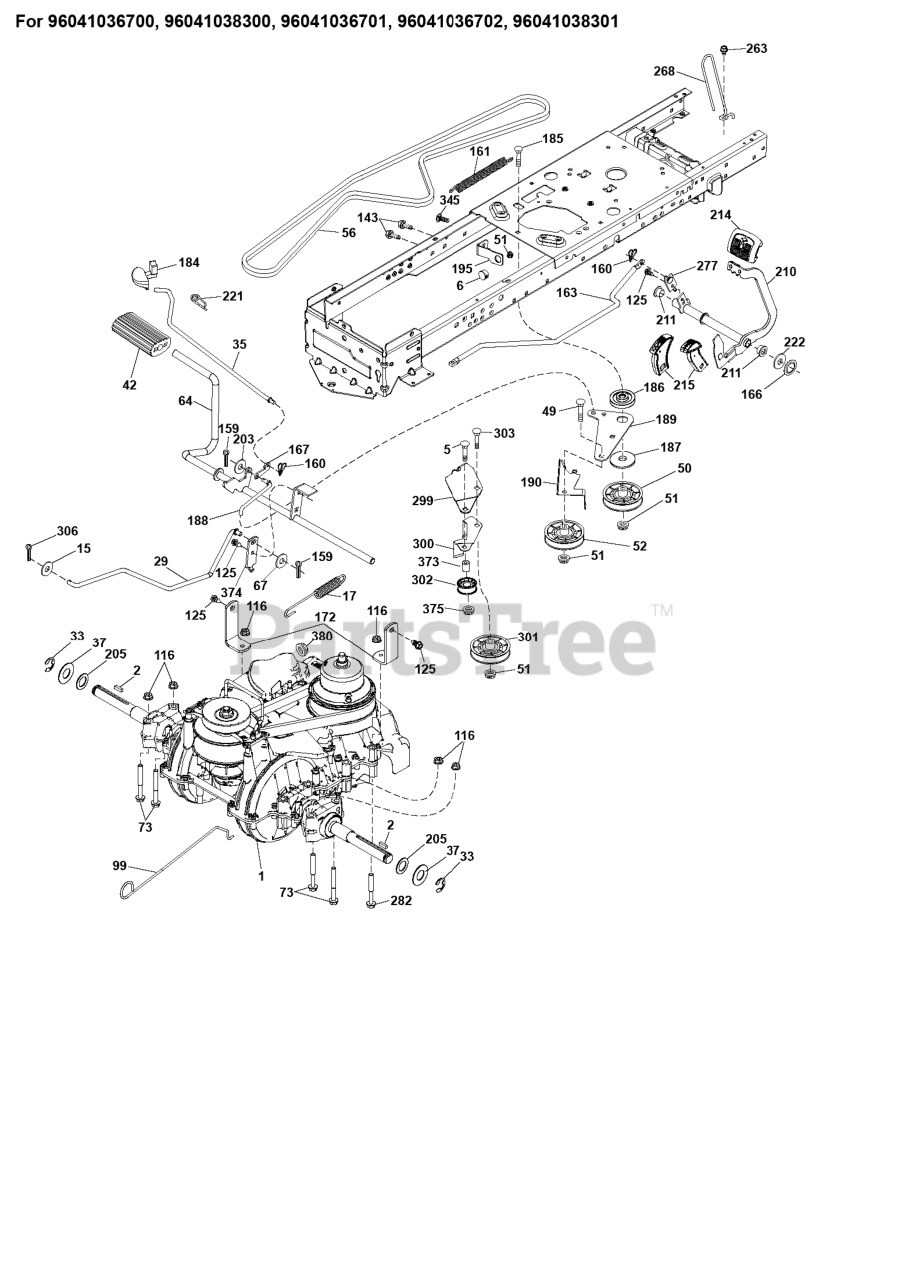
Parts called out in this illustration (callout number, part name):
1	TRANSAXLE.VARIATOR.PEDAL.SD
2	SQUARE KEY
6	BUSHING.SNAP.NYL.BLK.
15	WASHER
17	SPRING.BRAKE.VARIATOR
29	BRAKE.VARIATOR.SD3
35	ROD.CNTRL.PARK.PREDATOR.LT.TEX
37	WASHER.HARDENED
42	PEDAL COVER T
50	IDLER.FLAT.910.OFFSET
51	NUT LOCK FLG 3/8-16 UNC
52	IDLER.V-GROOVE.910.OFFSET
56	BELT.DRIVE.MOWER.TEX.42"
56	Belts
56	BELT.V.EURO.VARIATOR
64	SHAFT VARIATOR PEDAL CROSS
67	WASHER.NYLON;13/32X13/16X.109
73	BOLT HEX 5/16-18 GR 5
99	ROD.BYPASS.VARIATOR.GEN2
116	NUT LOCK HEX FLANGE 5/16-18
125	SCREW
143	Screw 5/16-18 x 1/2 Hex, Self Tapping 5/16-18 x 1/2
159	COTTER PIN
160	RETAINER CLIP
160	PIN COTTER;LOCKING;BOWTIE;1IN
161	SPRING, RETURN LT
163	ROD.CONTROL.PEDAL.VARIATOR
166	NUT.PUSH.625
167	LATCH.BRAKE.SPRING
172	STRAP.TORQUE.VARIATOR
184	HANDLE.PARKNG BRK.PRED.LT.428
186	SPACER.RETAINER
187	WASHER 12/32X2X10GA
188	LINK.CLUTCH.GROUND DRIVE.LONG
189	BELLCRANK.GROUND.DRIVE.TEX.
190	KEEPER.BELLCRANK.DRIVE
195	BRACKET.BRAKE.BRAKE.VAR.SD
203	WASHER
210	PEDAL.ASM.ROCKET.VARIATOR.LT
210	WELDMENT.PEDAL.VARIATOR.X431
211	BEARING.NYLON
214	PEDAL.FORWARD.PAD.TEX
215	CAP.PEDAL.REVERSE.VARIATOR
215	PEDAL.REVERSE.VARIATOR.MS428
221	RETAINER.SPRING.CLIP.H
222	WASHER 21/32 X 1-1/4 X 10 GA.
263	SCREW, 3/8-16X3/4
268	Mufflers
268	GUARD MUFFLER
277	SUBASM.LINK.ROCKER.PEDAL
282	BOLT HEX FLGHD 5/16-18X3 GR. 5
299	BRACKET.MOUNT.IDLERS
300	KEEPER.IDLERS.REAR.VARIATOR
301	PULLEY.IDLER.V-GROOVE
302	PULLEY.IDLER.FLAT.2"
303	BOLT CARRIAGE
306	PIN COTTER
373	SPACER.IDLER
374	ARM.CONTROL.BRAKE
380	NUT.PUSH.8MM
380	NUT.FLG.NYLOCK.1/4-20.GR.G.ZY
380	NUT FLG, NYLOCK, 1/4-20 GR G C
